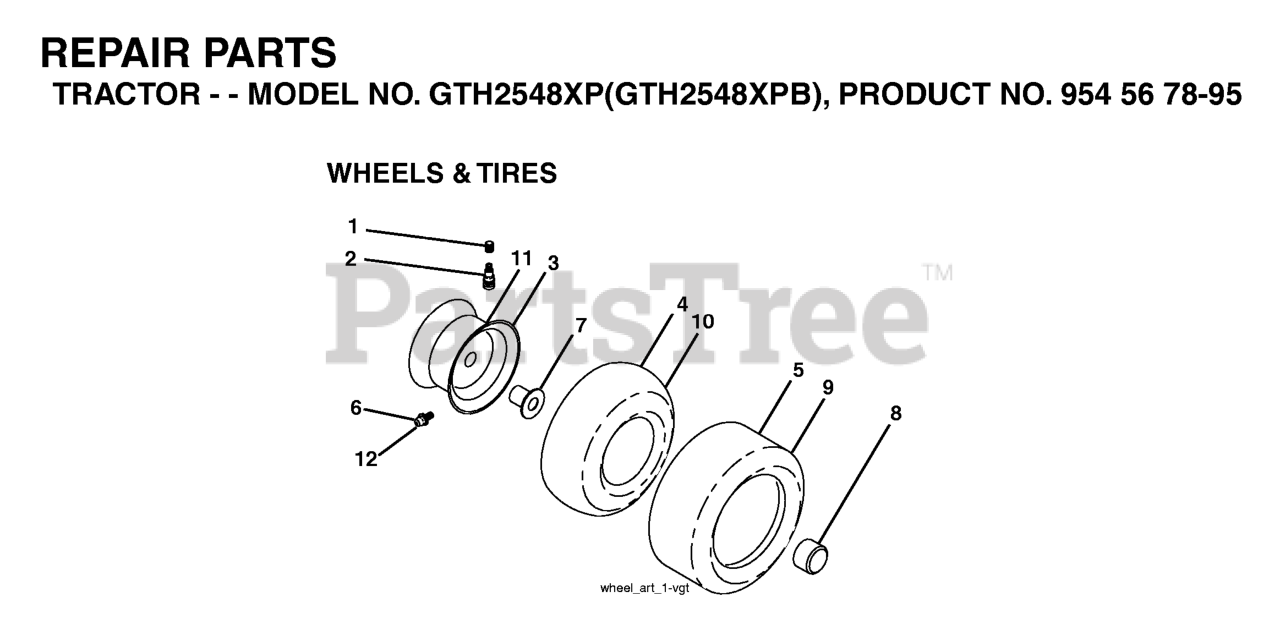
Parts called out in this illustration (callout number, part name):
2	VALVE STEM LT
4	TUBE.16X6.5/7.5-8
6	FITTING LT
7	BEARING T
8	CAP, AXLE BLK
10	TUBE.23X9.5-12
12	ZERK FITTING M
